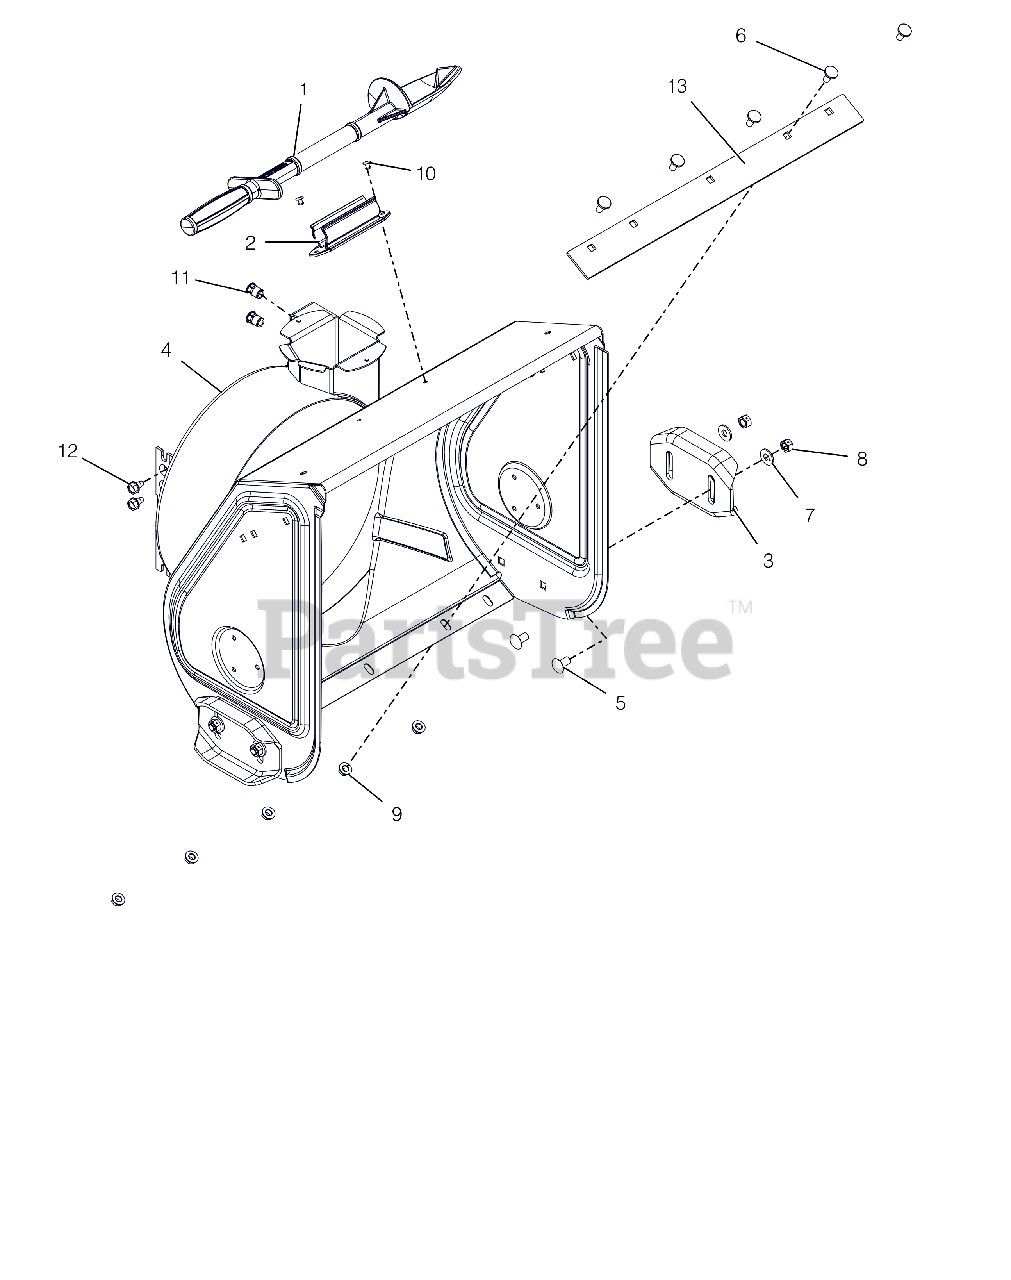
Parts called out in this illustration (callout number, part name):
1	DEVICE, SNOW CLEAN OUT
2	MOUNT, SNOW CLEAN OUT
3	SKID SHOE, REVERSIBLE - ORANGE
4	BLOWER HOUSING, 20" HB SERVICE
5	@BLT-RHDSSQNK .38-16X.75 G5YZ
6	BOLT, MODIFIED HEAD CARRIAGE
7	@WSHR-FL-STL.38X.875X.083 YWZC
8	@NUT-LK-CTR .38-16 YWZC
9	@NUT-LK-TOP-FLG .31-18 YWZC
10	RVT-POP .187 YZ
11	NUT, THREADED INSERT .38-16
12	@SCR-TAP .31-18X.50 HWH TR YWZ
13	SCRAPER BLADE, 20"
